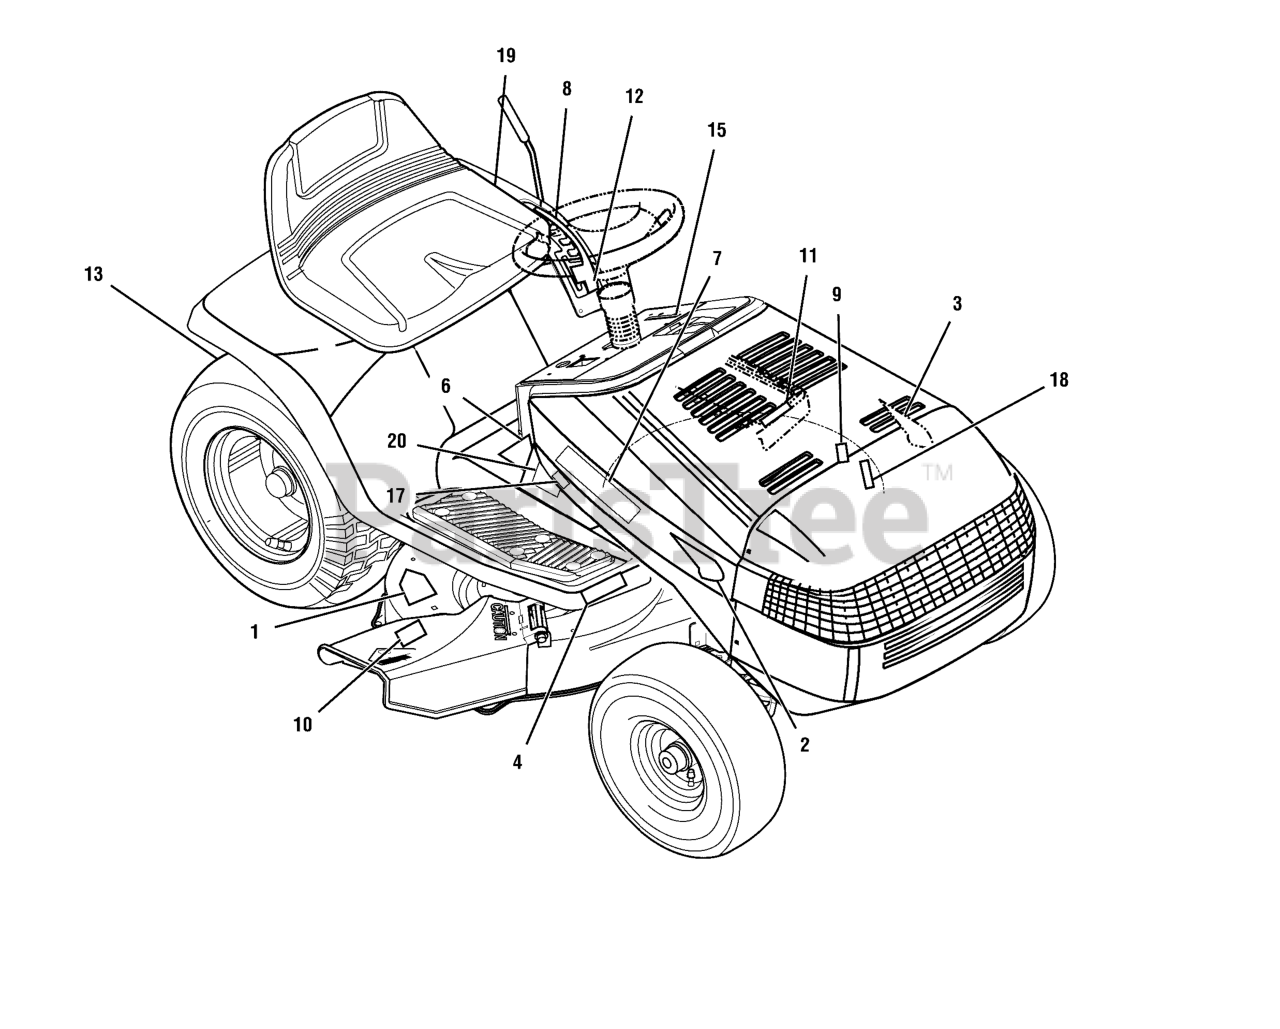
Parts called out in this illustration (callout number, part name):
1	DECAL, CUT FINGER ENGLISH
2	DECAL, MASPORT 14.5/40 RH
3	DECAL, MASPORT 14.5/40 LH
4	DECAL, 5 SPEED
6	DECAL, WARNING
7	DECAL, MASPORT LOGO
8	DECAL, 1/6 HGT ADJUST LIFT
9	DECAL, NO STEP LH HSNG
10	DECAL, NO STEP-CHUTE
11	DECAL, CLUTCH/BRAKE SILVER
12	DECAL, DECK LEVEL POS/ONLY
13	DECAL, WARNING LOAD LMT
15	DECAL, DASH SYMBOLS 3510
17	DECAL, V2-SS-1X3 CUTTING HEIGHT
18	DECAL, 3 WAY
19	DECAL, ENGAGE PTO
20	DECAL, BRIGGS LOGO
